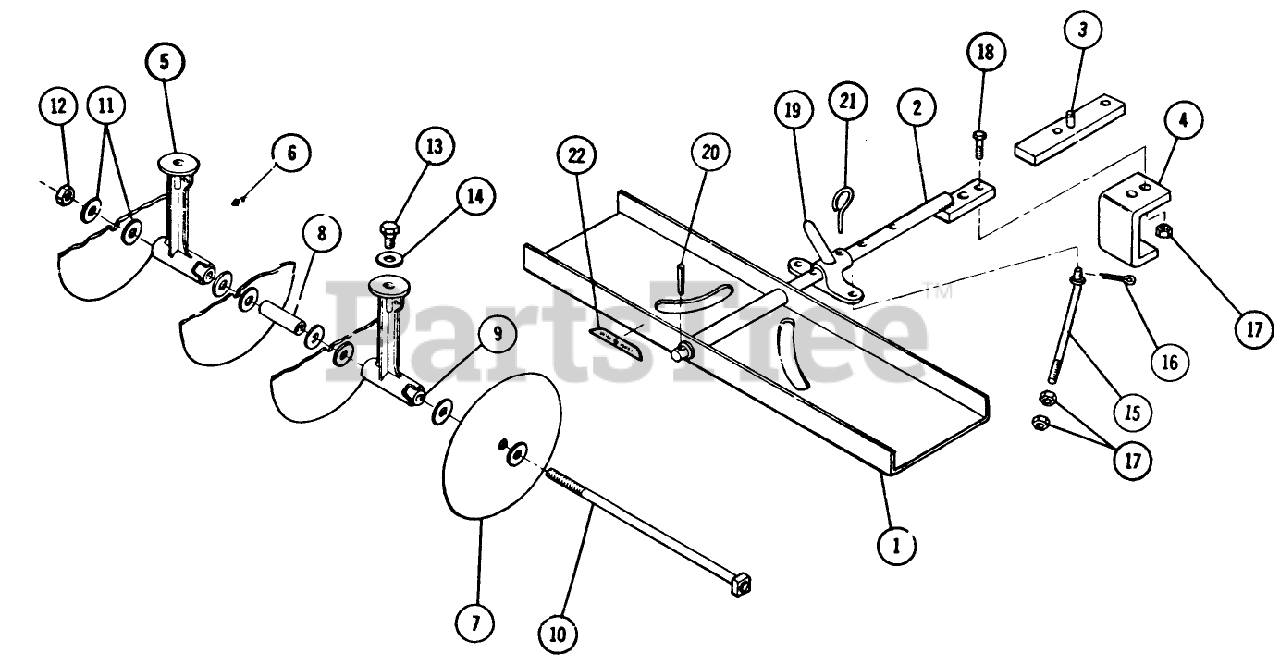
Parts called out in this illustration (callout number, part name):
1	Channel
5	Gang-Disc
8	Spacer
10	Bolt
11	Washer 3/4 U. S.
12	Nut 3/4-10 Elastic Stop
13	Bolt Shoulder 5/8-11
16	Cotter Pin
17	Locknut-1/2-13
18	Bolt-1/2-13-1 3/4
20	ROLL PIN 1/4 X 1-1/4
